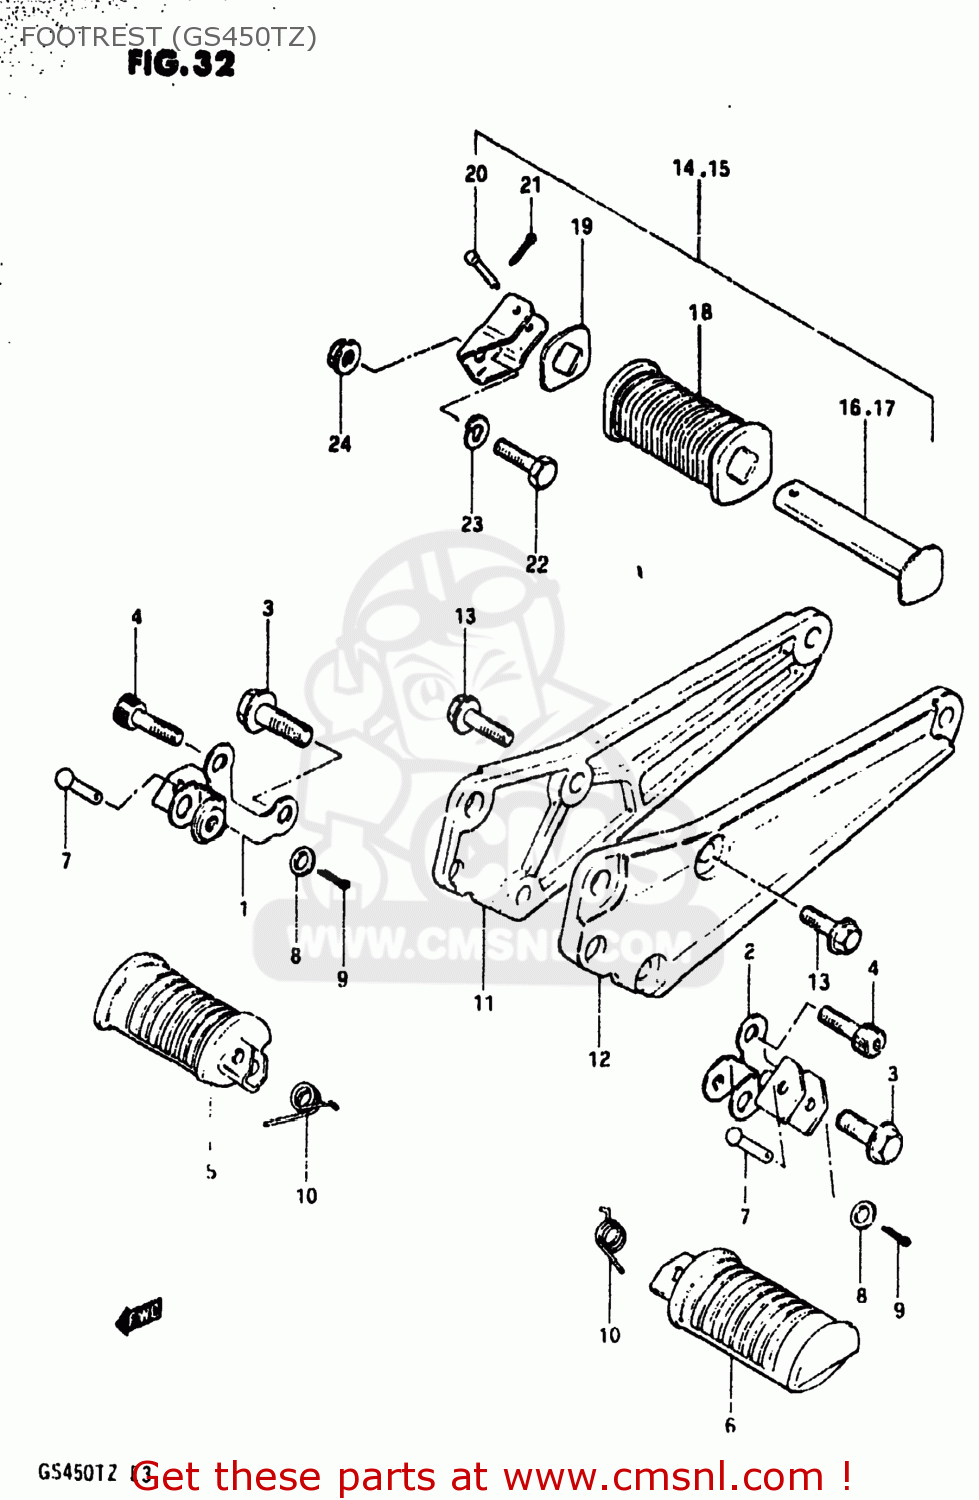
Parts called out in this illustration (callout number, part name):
1	BAR,FRONT FOOTREST
2	BAR,FRONT FOOTREST,LEFT
3	BOLT
4	BOLT
5	RUBBER,FRONT FOOTREST
6	FOOTREST
7	PIN
8	WASHER
9	PIN
10	SPRING
11	BRACKET,MUFFLER,RIGHT
12	BRACKET,MUFFLER,LEFT
13	BOLT
14	FOOTREST ASSY,PILLION,R
15	FOOTREST ASSY,PILLION,L
16	BAR,REAR FOOTREST,RIGHT
17	BAR,REAR FOOTREST,LEFT
18	RUBBER,PILLION FOOTREST
19	WASHER,FOOTREST RUBBER
20	PIN
21	PIN
22	BOLT,M10X1.25X
23	LOCK WASHER
24	NUT
